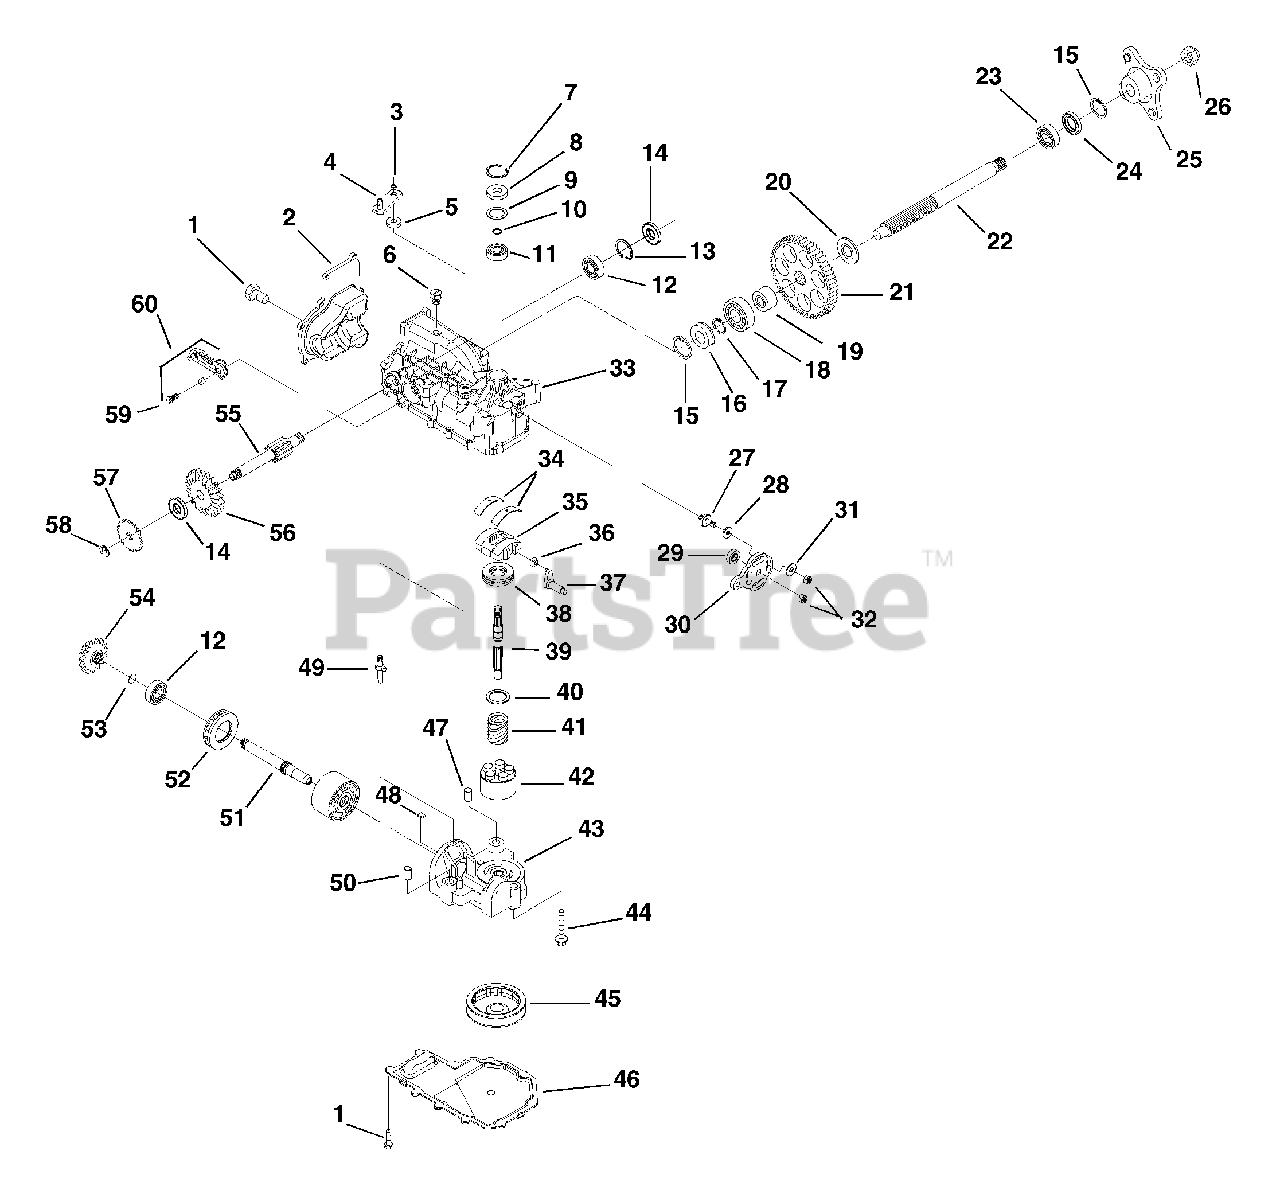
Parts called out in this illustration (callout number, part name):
1	Screw 1/4-20 x .75
2	Cover-Back
3	Ring-Retaining
4	Arm-Bypass
5	Seal-Lip
6	Plug-Plastic
7	Ring-Retaining
10	Ring-Wire Retaining
11	Bearing-Ball
12	Bearing-Ball
13	Ring-Retaining
14	Seal-Brake Shaft
15	Ring-Retaining - Axle
16	Seal-Plug - Side
17	Ring-Retaining - Axle
18	Bearing-Ball 20 x 47 x 14
19	Bushing-Axle
20	Gear-Spur 53T
21	Bushing-Axle
22	Shaft-Axle
23	Bearing-Ball 25 x 47 x 12
25	Assembly-Hub
26	Nut-Hex 3/4-16
27	Stud-Short 5/16-24
28	Friction Puck
30	Arm-Control
31	Washer
33	Assembly-Upper Housing
34	Bearing-Cradle
35	Variable Swashplate
36	Slot Guide
37	Arm-Trunnion
38	Bearing-Thrust 30 x 52 x 13
39	Shaft-Input
40	Washer-Block Thrust
41	Spring-Block
42	Assembly-Cylinder Block 10cc
43	Assembly-Center Section
45	Filter
46	Housing-Lower
47	Pin-Alignment
48	Bypass Plate
49	Bypass Actuator
50	Assembly-Cylinder Block 21cc
51	Shaft-Motor
52	Bearing-Thrust 42 x 68 x 16
53	Ring-Wire Retaining
54	Gear-Bevel 14T
55	Kit, Brake Shaft
56	Gear-Bevel 19T
57	Brake Disc
58	Ring-Retaining
59	Screw-He-Washer-Head 1/4-20 x 7/8
60	Assembly-Left Hand Brake Arm
